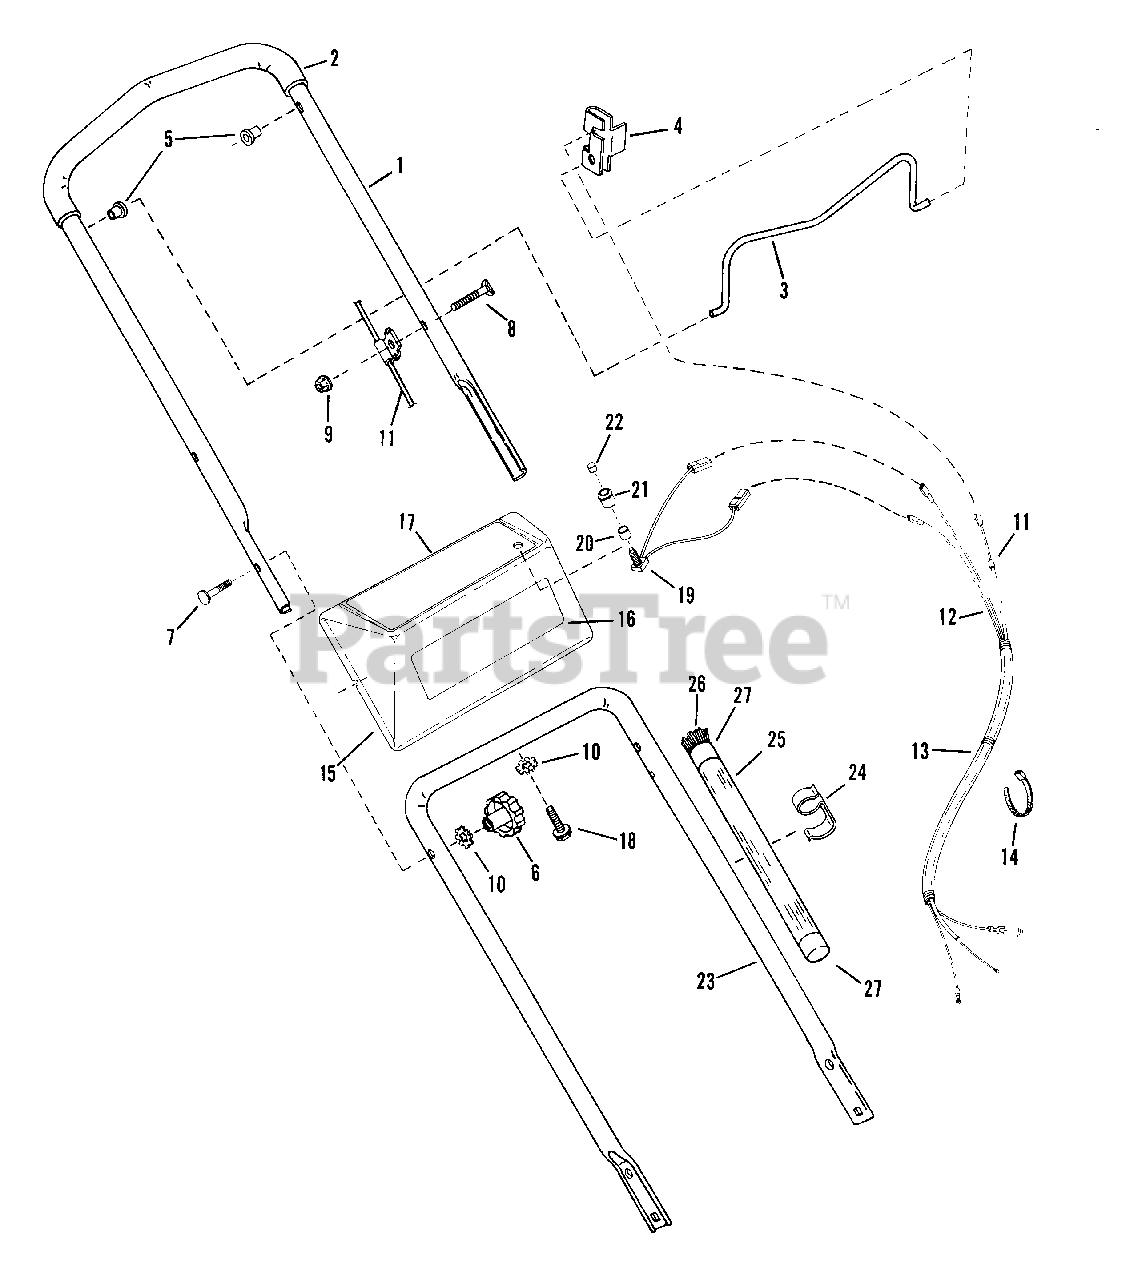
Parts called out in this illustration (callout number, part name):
1	HANDLE, Upper
2	GRIP, Foam
3	BAIL, Throttle
4	CLIP, Throttle
5	BUSHING, Bail
6	KNOB, 5/16-18 Plastic
7	BOLT, 5/16-18 x 2" Curved Head
8	BOLT, 1/4-20 x 1-1/2" Curved Head
9	NUT, 1/4-20 Hex Flange Lock
10	WASHER, 5/16 Int./Ext. Tooth Lock
11	ASSEMBLY, Throttle Cable
12	HARNESS, Wire
13	SHEATH, Harness
14	TIE, Cable
15	ASSEMBLY, Panel/Label
16	LABEL, Model
17	LABEL, Instruction
18	SCREW, 5/16-18 x 5/8" Self-Tapping
20	SPACER, Switch
21	BEZEL, Switch
22	CAP, Switch
23	HANDLE, Lower
24	CLIP, Wire
25	TUBE, Plastic
26	LINE, .105 DIA. (50 PIECES)
27	CAP, Tube
